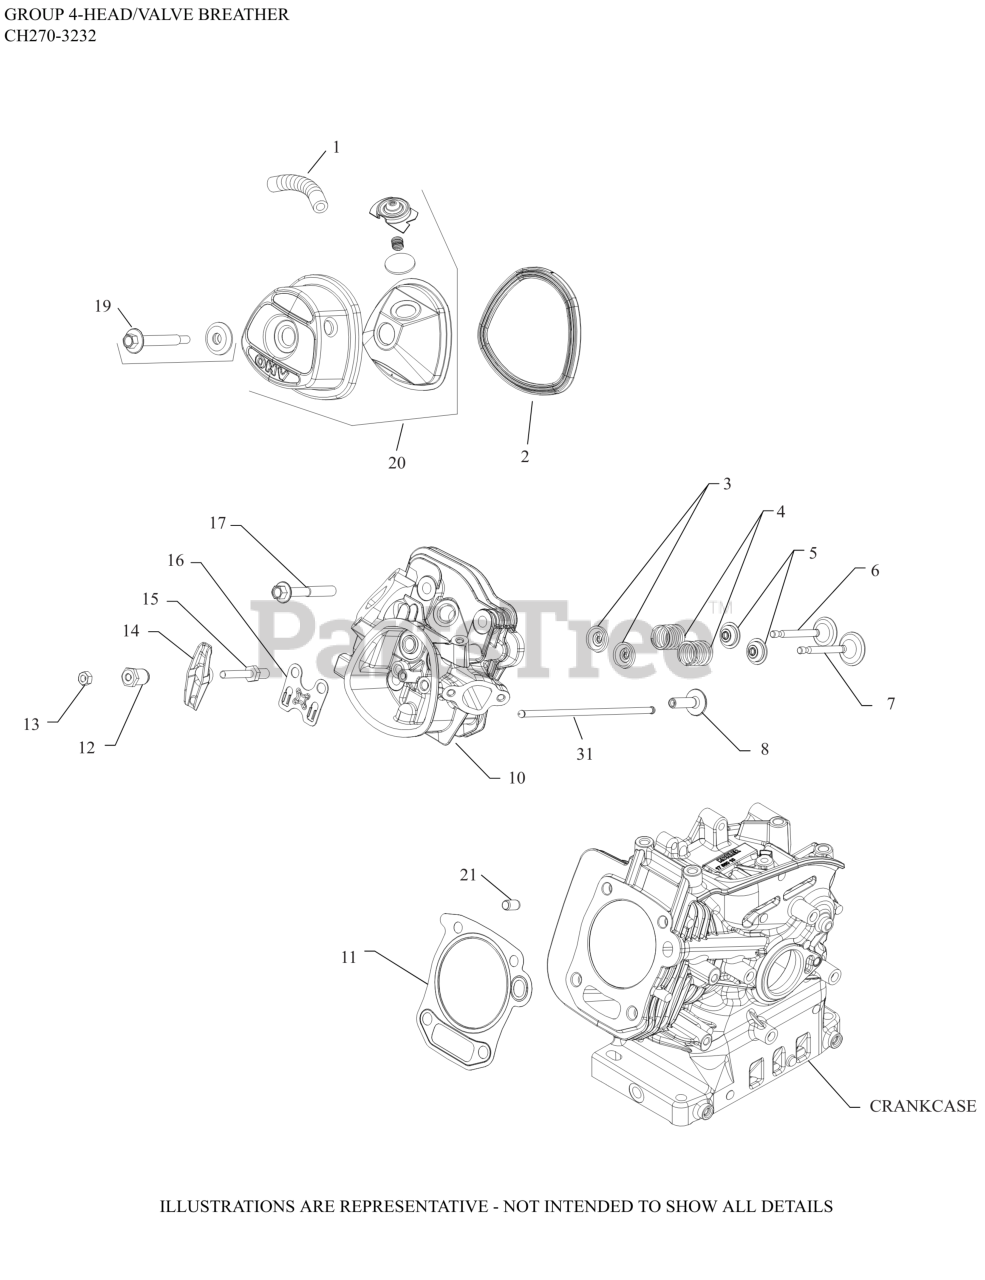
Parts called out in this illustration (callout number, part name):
1	TUBE, BREATHER - (#1812313S)
2	GASKET, VALVE COVER
3	RETAINER, VALVE SPRING
4	SPRING, VALVE
5	SEAL, VALVE STEM
6	VALVE, EXHAUST
7	VALVE, INTAKE
8	LIFTER, VALVE
10	KIT, HEAD AND VALVE TRAIN
11	KIT, HEAD GASKET
12	PIVOT, ROCKER ARM
13	NUT, HEX JAM
14	ARM, ROCKER
15	STUD, ROCKER ARM-USE 14 072 22-S
16	PLATE, PUSHROD GUIDE
17	SCREW, HEX FLANGE CYL HEAD
19	SCREW, VALVE COVER SEAL ASSY
20	KIT, VALVE COVER
21	DOWEL, CYLINDER HEAD
31	ROD, PUSH
